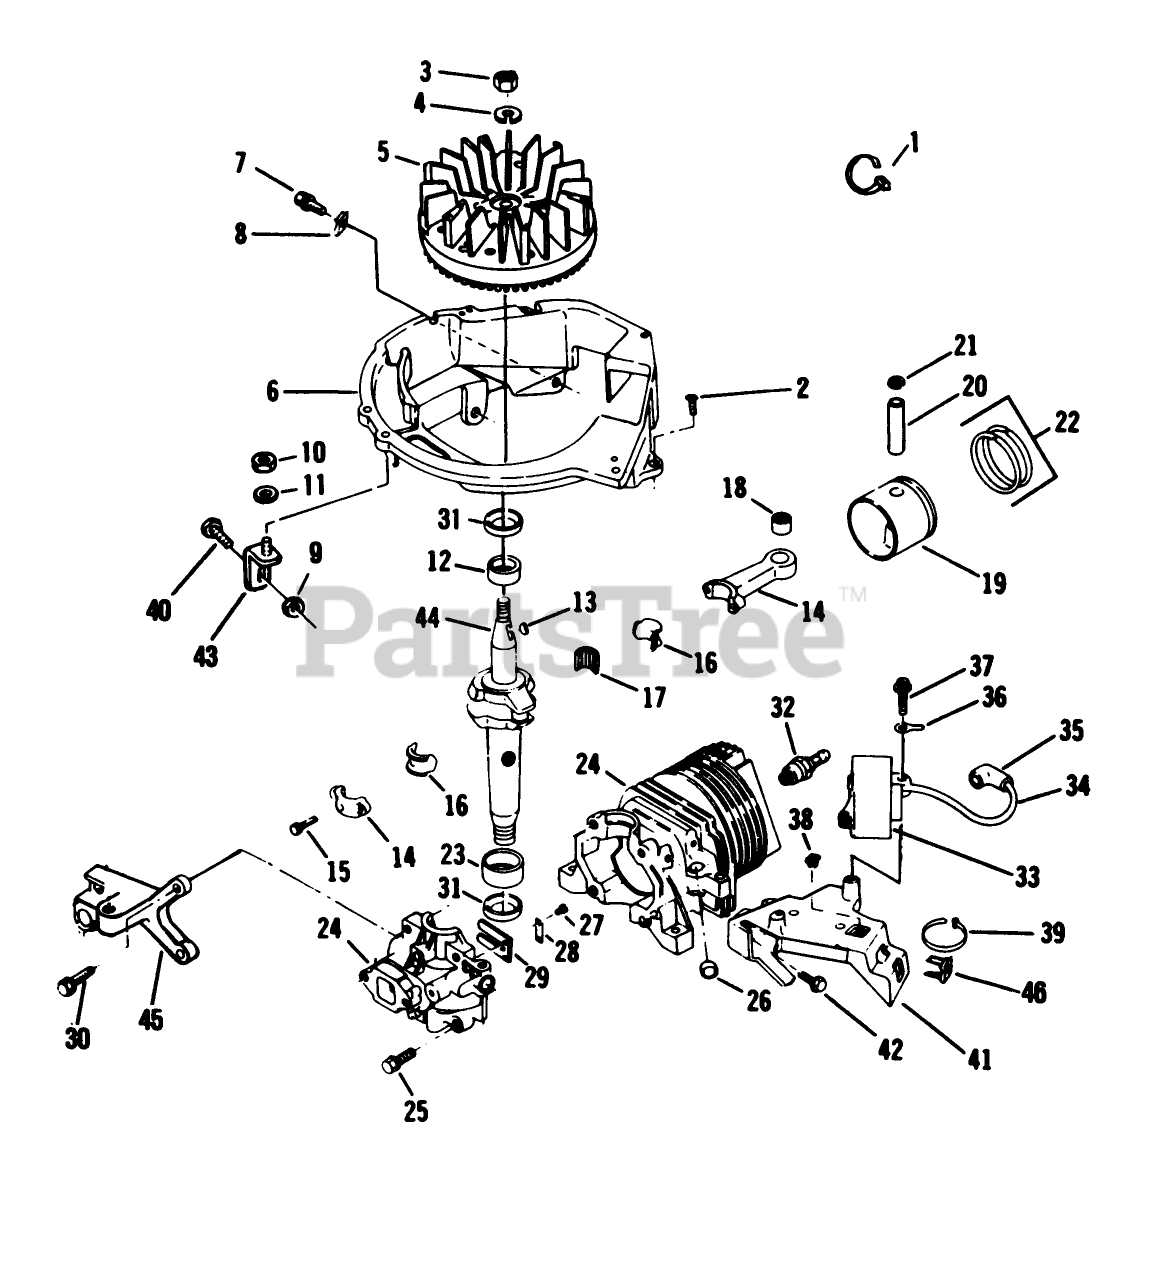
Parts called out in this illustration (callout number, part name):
2	SCREW F
3	NUT
5	FLYWHEEL ASSY F
7	SCREW-SEMS
9	NUT-LOCK F
10	LOCKNUT E
11	WASHER S
12	BEARING V
13	KEY
15	SCREW-HSH
16	LINER ASM
18	BEARING AY F
21	RING-RETAINING
23	BEARING V
25	SCREW S
26	PLUG-CORE VF
28	PLATE-BACKUP, REED
31	SEAL-OIL
34	HT LEAD&COVER XEV
36	TERMINAL S
38	NUT-CLIP
40	BOLT F
43	BRACE AY F
45	BRACKET-BRAKE F
46	NUT-CLIP
